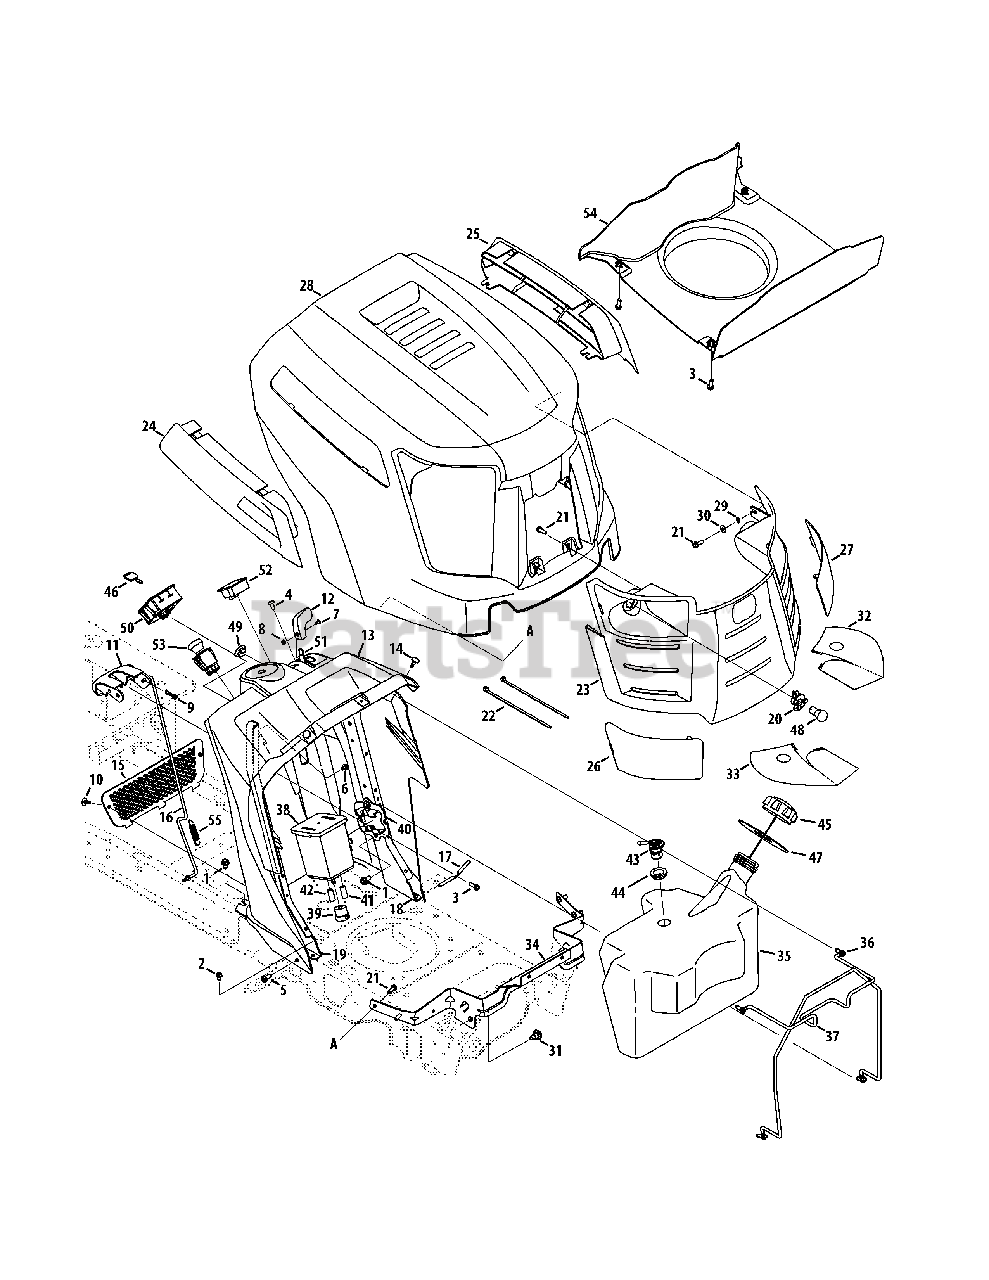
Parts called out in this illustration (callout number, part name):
1	Screw, Self-tapping, 5/16-18, .750
2	Screw, Self-tapping, 1/4-20, 0.500
3	Screw, HL, 1/4-15, 0.750
4	Screw, Ab, 1/4-14, 0.625,
5	Screw, Self-tapping, 5/16-18, 0.750,
6	Screw, Self-tapping, 1/4-20 x .625
7	Screw, Mach, #8-32, 0.375
8	Nut, Hex, #8-32
9	Pin, Cotter, Bow-Tie 72
10	Clip, Ratchet, .250 Dia
11	Lever, Dash, Cruise/Brake
12	Knob, Throttle
13	Dash Panel, A-Style, Elect PTO
14	Bumper, .62 Dia X .3
16	Rod, Control, Latch Cub
17	Rod, Lever, Bent
18	Support, Dash, Plate LH
19	Support, Dash, Plate RH
20	Socket, Lamp
21	Screw, 1/4 Dia, .750
22	Tie, Cable, Push Mount 7.5 Lg
23	Grille Ass’y (Incl. 26, 27, 32 & 33)
24	Scoop, Hood, RH A-Style
25	Scoop, Hood, LH A-Style
26	Lens, Hood, RH A-Style
27	Lens, Hood, LH A-Style
28	Hood, A-Style
29	Washer, Lock, 1/4, External
30	Washer, Flat, .271, .630, .065
31	Screw, Shoulder, .43x.29, 5/16-18
32	Reflector, Cub A Style, LH
33	Reflector, Cub A Style, RH
34	Bracket, Pivot, Hood A-Style
35	Tank, Fuel, 3.75 Gal.
35	Tank, Fuel, 3.30 Gal. (CA)
36	Screw, Self-tapping, 1/4-20, .625
36	Screw, Self-tapping, 1/4-20, .75 (CA)
37	Rod, Support, Fuel Tank
38	Canister, Carbon, 5 Gallon (CA)
39	Filter, Vent, Canister (CA)
40	Bracket, Adapter, Canister (CA)
41	Hose, Fuel, Low Perm, 3/16 Wht (CA)
42	Hose, Fuel, Low Perm, 7/32 Yel (CA)
43	Valve, Rollover Grommet (CA)
44	Grommet, Rubber, 23.0 ID (CA)
45	Cap, Fuel
45	Cap, Fuel (CA)
46	Key, Ignition
47	Gasket, Fuel Tank
48	Lamp, 12v
49	Plug, Choke
49	Control, Choke, 40.5 x 2, Yellow
50	Module Switch, Ignition
51	Cable, Throttle/Choke, 38"
51	Cable, Throttle, 38"
52	Meter, Indicator
53	Switch, Electric PTO, Yellow
54	Plenum, A-Style
55	Spring, .500 Dia. x 2.733
